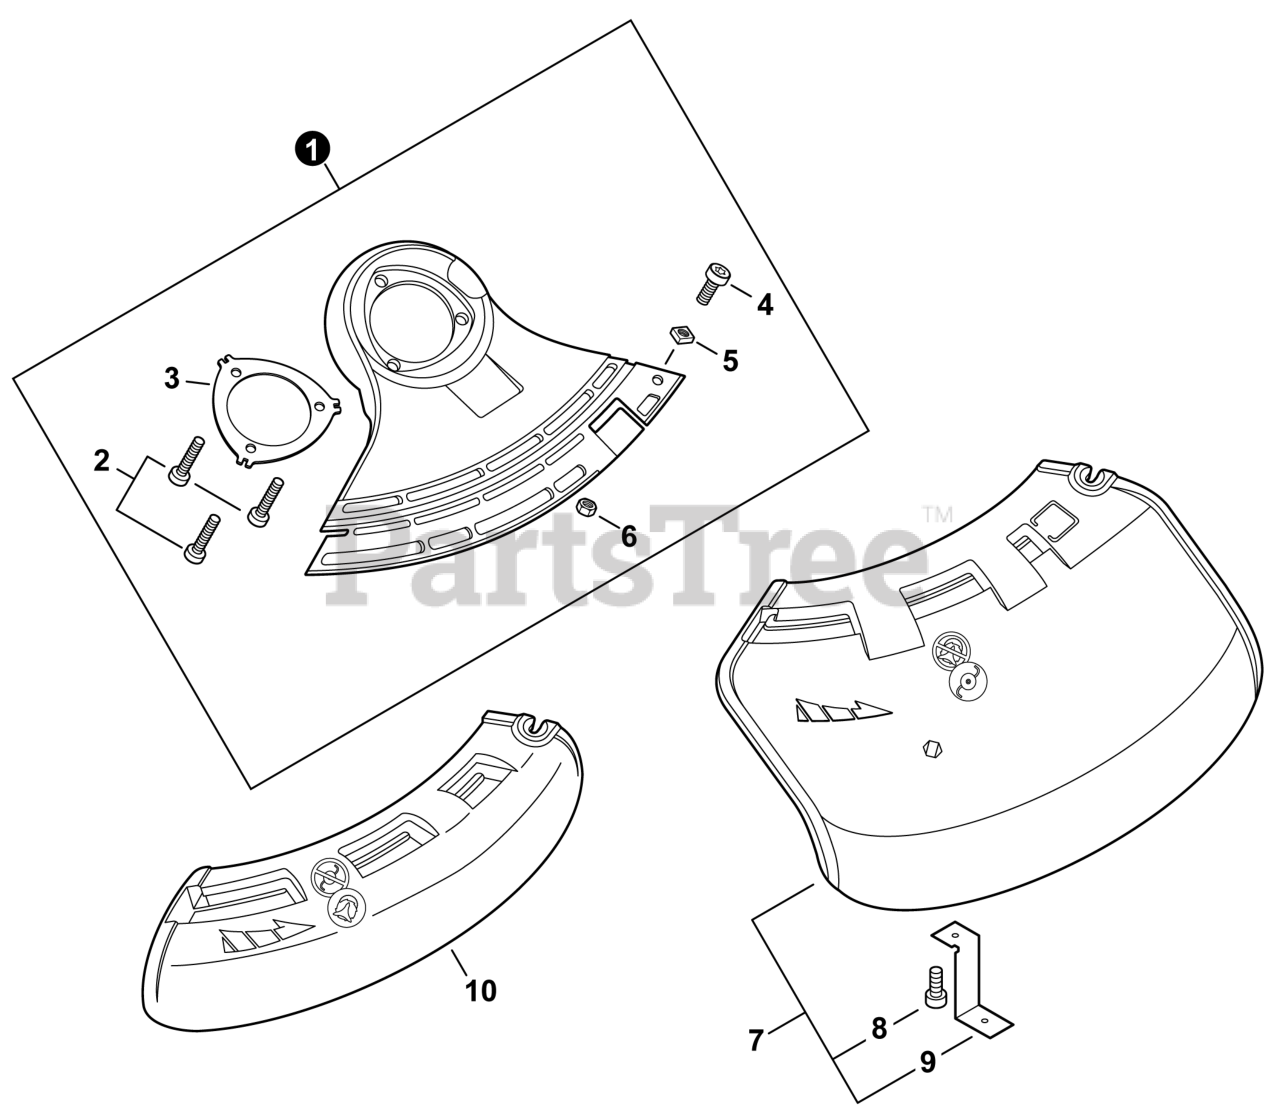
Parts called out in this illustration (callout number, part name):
1	BASE ASSY, DEBRIS SHIELD
2	BOLT, TORX 5x16
3	PLATE, SHIELD
4	BOLT, TORX 5x25
5	NUT - 5 - SQUARE
6	NUT, LOCK M5
7	SHIELD ASSY, DEBRIS - TRIMMER EXTENSION
8	BOLT, TORX 5x16
9	CUTTER, LINE
10	SHIELD, DEBRIS - BLADE EXTENSION
